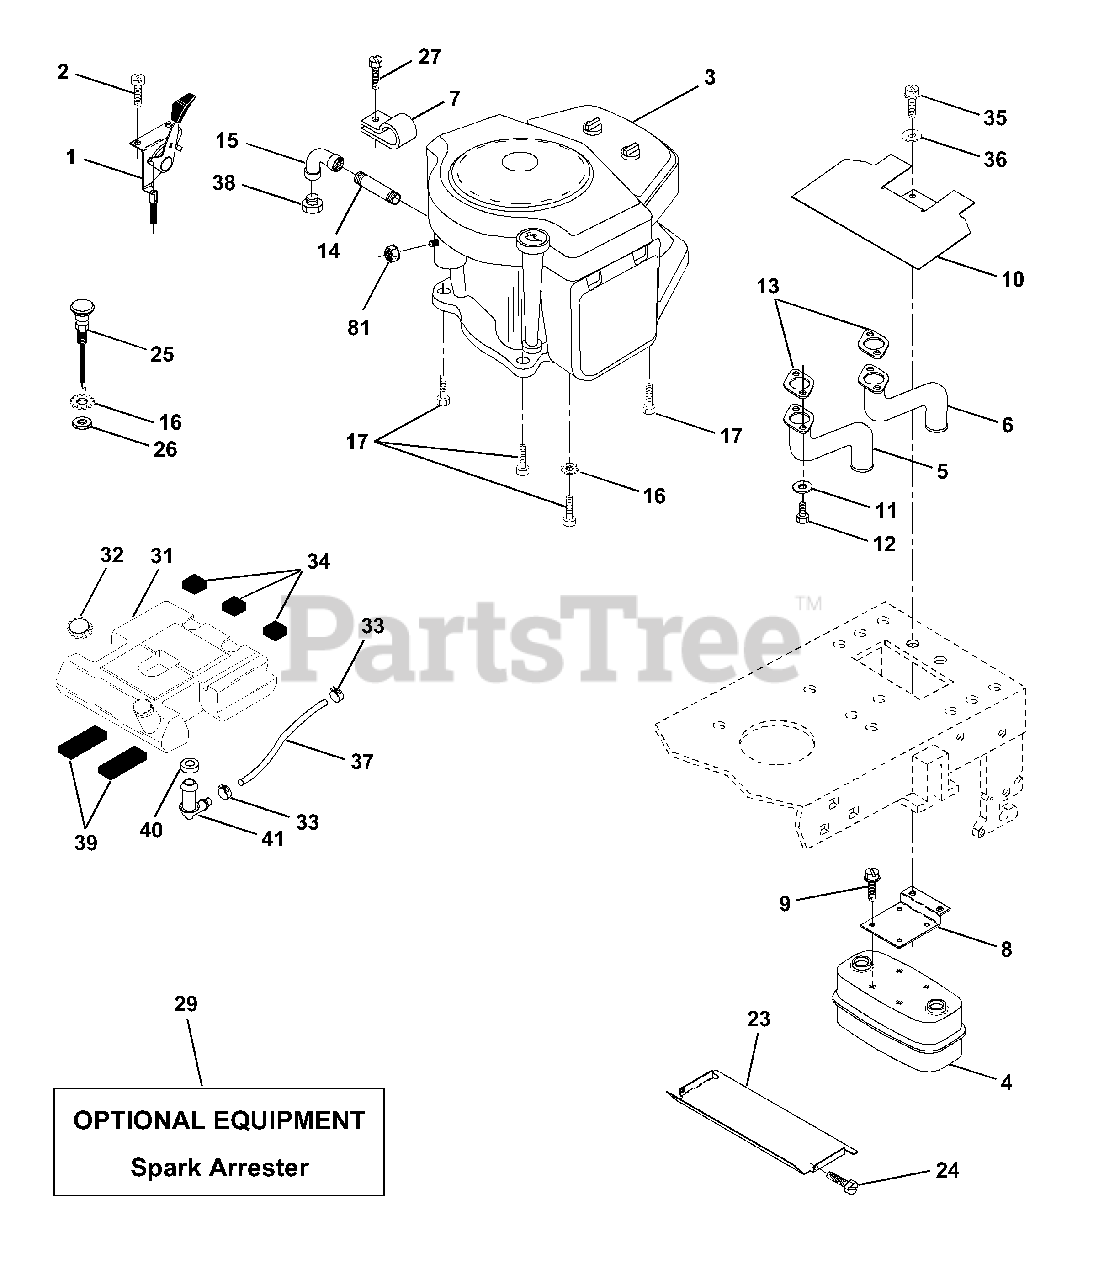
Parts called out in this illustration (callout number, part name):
1	Control RH Blk Flg
2	Screw Hex Thd Cut 1/4-20x5/8 T
4	Muffler VGT YT Dual Inlet
5	Exhaust Asm LH
6	Exhaust Asm RH
7	Clamp Tube Double Engine
8	Bracket Muffler Mounting
9	Screw Hex Wsh Thd Cut 1/4-20
10	Shield Heat LT
11	Washer, Lock Hvy HLCL Spr. 1/4
12	Bolt Fin Hex 1/4-20 x .75
13	Muffler Gasket
14	Nipple Pipe 3/8 Npt X 4-1/2"
15	Elbow Std 90 Degree 3/8-18 Npt
16	Washer Lock Ext Tooth 3/8
17	Screw thdrol 3/8-16 x 1-1/2 TT
23	Shield Heat Browning LT/YT
24	Screw Tap Hex #10-24unc X 1/2
25	Choke Control
26	Nut, Fin Hex 3/8-24 Unf
27	Screw Slftp #10-24 x 1/2 Tt-B
29	Kit Spark Arrestor (Flat Scrn)
31	Tank Fuel 3 50 Rear
32	Cap Asm Fuel
33	Clamp Hose Blk
34	Pad, Spacer
35	Screw Thdrol 5/16-18 x 3/4
36	Washer 13/32 x 1-1/4 x 12 Ga.
37	Line Fuel 54"
38	Plug Oil Drain
39	Pad, Idler
40	Bushing
41	Stem Tank Fuel
81	Nut Keps Hex 1/4-20 UNC
